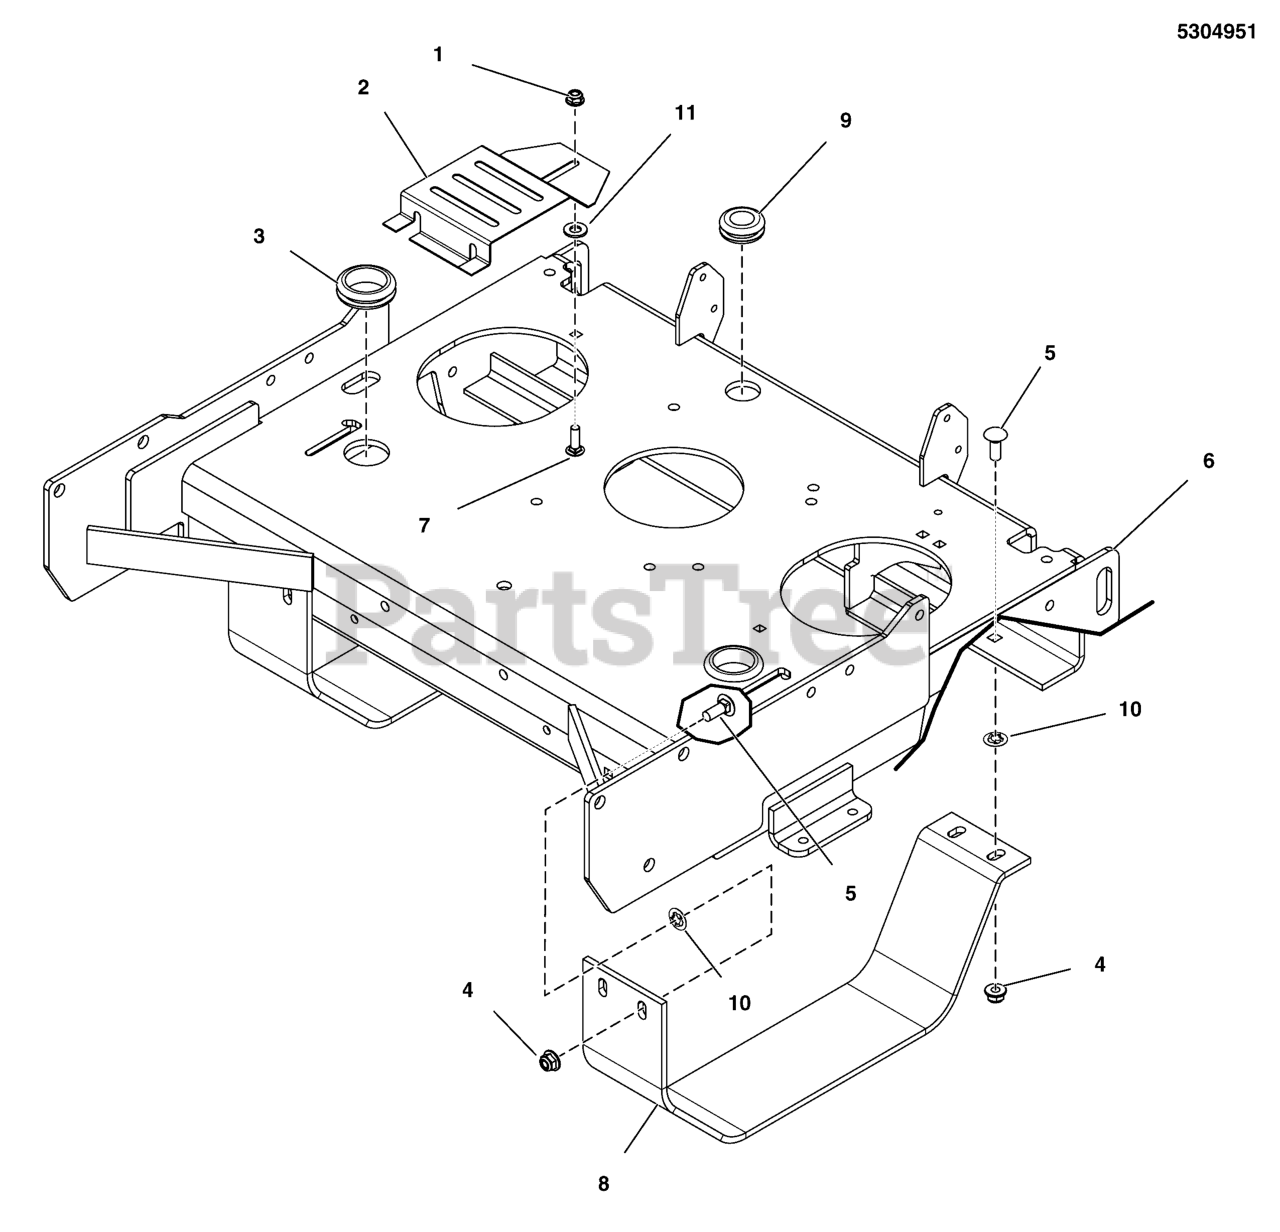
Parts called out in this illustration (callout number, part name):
1	NUT, 5/16-18 HEX NYLOCK FLANGE
2	PLATE, FAN GUARD - BLK
3	GROMMET, 1-1/2" ID FOR 1/4" METAL
4	NUT, 3/8-16 HEX NYLOCK FLANGE
5	BOLT,3/8-16X1.000,RND HD CRRG,ZINC/CLEAR
6	WELD, ENGINE DECK, W35 - RED
7	BOLT, 5/16-18 X 1, CARRIAGE
8	PLATE, TRANS GUARD, SW30 - BLK
9	GROMMET, 7/8"ID, 1/4" THICK STK
10	RETAINER,3/8,PUSHNUT,ZINC/CLEAR
11	5/16 PUSH-ON NUT RETAINER, STL, CZ
